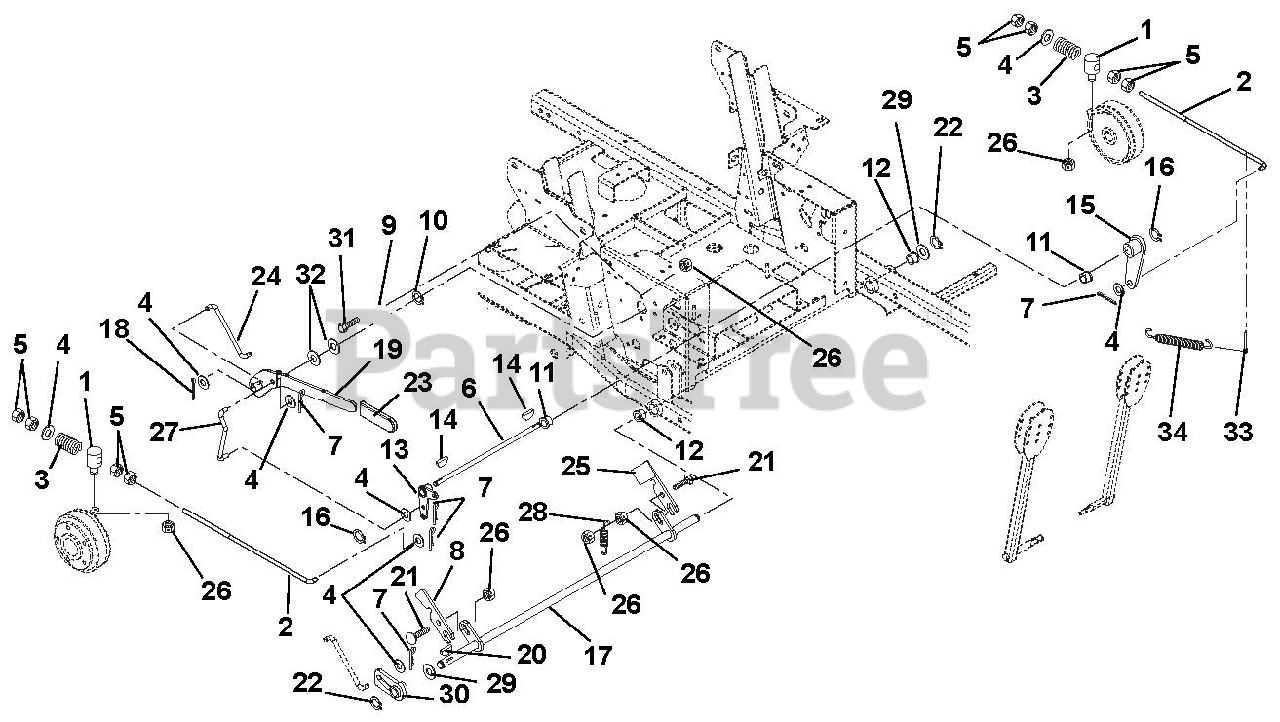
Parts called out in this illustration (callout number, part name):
1	Pivot, Brake Rod
2	Rod, Brake .38 x 19.00
3	Spring, Compression .142 x .710 x 1.75
4	Washer, Flat Steel .406 x .812 x .065
5	Nut, Hex .38-16
6	Shaft, Brake 2.00
7	Pin, Hair
8	Slide, Interlocking Brake
9	Bushing, Flange
10	Ring, Retaining External .625 x .05
11	Bushing, Flange Nylon .762 x 1.00 x .58 x 1.48
12	Bushing, Flange .515 x .75 x .745 x 1.00
13	Weldment, 200 Brake ACT. Arm
14	Key, Square .188X1.00X.188 SAE 8630
15	Arm, Brake Left Hand
16	Ring, Retaining External .625 x .050
17	Weldment, Mechanical Brake
18	Pin, Cotter External .09 x .75
19	Weldment, Brake Handle
20	Key, Woodruff .13 x .63
21	Bolt, Round Head Square Neck .31-18 x 1.25 Grade 5
22	Ring, Retaining External .50 x .05
23	Grip, Handle
24	Linkage, Brake Actuating
25	Interlock, Safety Switch
26	Nut, Locking Top Flange .31-18
27	Linkage, Brake Actuating
28	Spring, Tension .063 x .44 x 1.56
29	Washer, Flat Steel .505 x 1.00 x .062
30	Weldment, Parking Brake Hub
31	Bolt, Hex .31-18 x .75 Grade 5
32	Washer, Flat Steel .630 x 1.250 x .062
33	Pin, Cotter .12 x .75 Extended Prong Square Cut
34	Spring, Extension
